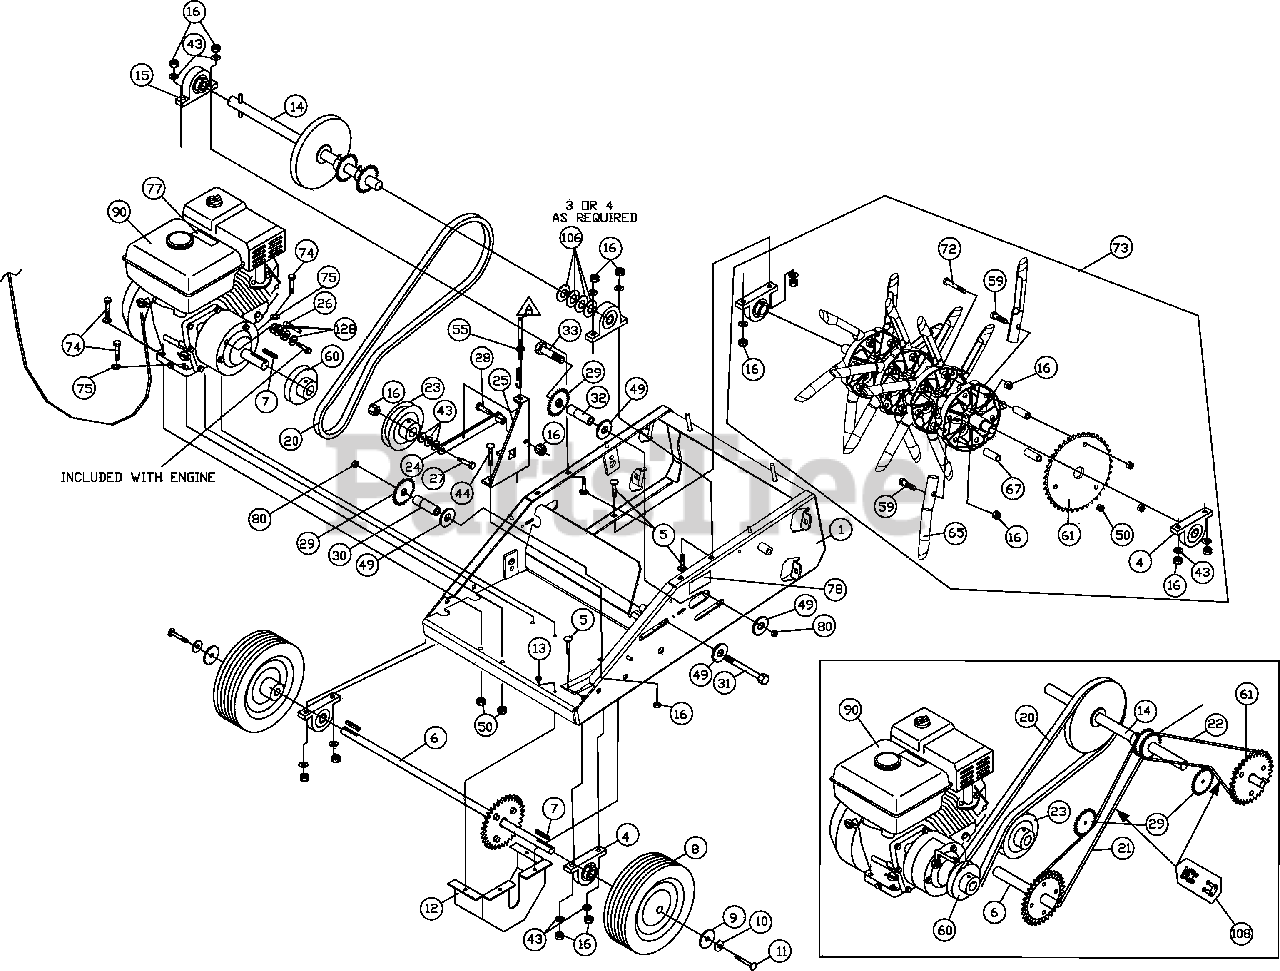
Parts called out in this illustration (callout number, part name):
1	FRAME ASSEMBLY WA AE402
4	BEARING 3/4" PILLOW BLOCK
5	CARRIAGE BOLT 3/8-16 x 1 1/2
6	FRONT AXLE ASSY
7	KEY SQUARE 3/16 x 3/16 x 1.25
8	WHEEL 10.5" SEMI PN. W3/4" KEYED HUB
9	FENDER WASHER 5/16"
10	WASHER LOCK 5/16 TWISTED TOOTH
11	SCREWCAP 5/16-18 x 1"
12	GUARD DIFFERENTIAL AE
13	SCREW SELF TAP 1/4 x 1/2"
14	JACKSHAFT AERATOR ASSY
15	BEARING 1" PILLOW BLOCK
16	NUT LOCK 3/8-16
20	BELT 4L x 43" POWER RATED
21	CHAIN #40 x 94 PITCH O-RING (WHEEL)
22	CHAIN #40 x 76 PITCH O-RING (TINE)
23	PULLEY IDLER 4.5"
24	ARM IDLER WA
25	BRACKET MOUNT IDLER
26	BELT FINGER FRONT AE
27	SCREWCAP 3/8"-16 X 2" HCS ZP
28	BOLT SHOULDER 1/2 x 1
29	SPROCKET IDLER 17T x 5/8" BORE
30	SPACER SPROCKET IDLER 2.5"
31	SCREW CAP 1/2 - 13 x 4
32	SPACER SPROCKET IDLER 1.175"
33	SCREW CAP 1/2 - 13 x 3"
43	WASHER FLAT 3/8 SAE
44	CARRIAGE BOLT 3/8"-16 X 1"
49	FLAT WASHER 1/2"
50	NUT LOCK 5/16-18
55	CABLE CLUTCH ASSY
59	PART NOT APPLICABLE ON THIS MODEL
60	PULLEY ENGINE
61	SPROCKET 42 T
62	SPACER - TINE SPROCKET 1.468
63	SCREWCAP 5/16-18 X 2 1/2" HCS ZP
64	TINE PLATE
66	SPACER - NUT RIGHT END
67	SPACER - BETWEEN TINE ASSEMBLIES
69	HEAVY WASHER TINE ASSY
70	WASHER LOCK 7/8" INTERNAL
71	NUT JAM 7/8 -14 (Torque 100 ft.lbs)
72	CARRIAGE BOLT 5/16-18X1.75
73	SHAFT TINE DRIVE
74	SCREW CAP 5/16 - 18 x 1.5"
75	WASHER FLAT CUT 5/16
77	PART NOT APPLICABLE ON THIS MODEL
78	LABEL DANGER GUARD
80	NUT LOCK 1/2 -13 THIN
81	SPACER BEARING/SPROCKET 0.375 THK
106	WASHER 1.062" ID X 1.75 OD
108	CHAIN MASTER LINK
119	SPACER - TINE PLATES
120	TINE ASSY (INCLUDES 50,64,65,72,&119)
128	WASHER 1/4" FC
